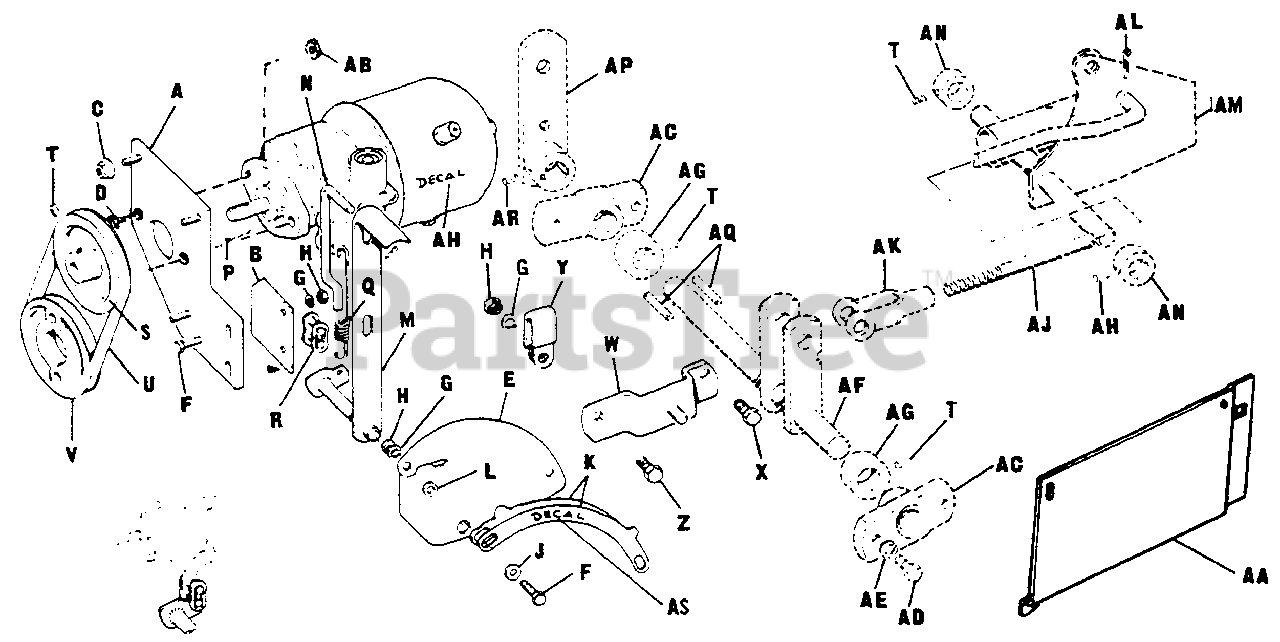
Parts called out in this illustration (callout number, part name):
A	Pump Support Assembly
B	Angle Bracket
C	Hex. Nut, Whiz Lock, 5/16"-18
D	Machine Screw, Flat Hd. 3/8-16 x 1-1/4" lg.
F	Hex. Cap Screw, 1/4"-20 x 3/4"
G	Lock Washer, 1/4"
H	Full Hex. Nut, 1/4"-20
J	Plain Washer, 1/4"
K	Stop Plate
M	Lever Assembly
N	Latch Rod
P	Cotter Pin, 3/32" x 5/8"
R	Connecting Link
S	Pump Pulley
T	Set Screw, 5/16"-18 x 5/16"
V	Drive Pulley
W	Pivot Bar Assembly
X	Hex. Cap Screw, 5/16"-18 x 1"
Y	Hose Clamp
Z	Hex Cap Screw, 1/4"-20 x 1"
AA	Panel, Side L. H.
AB	Nut, Whiz-Lock, Flange, 3/8-16
AC	Lift Lever Bearing
AD	Hex. Cap Screw, 3/8"-16 x 7/8"
AE	Lock Washer, 3/8"
AF	Lift Shaft Assembly
AG	Set Collar
AJ	Lift Rod (497 only)
AK	Adj. Yoke End (497 only)
AL	Cotter Pin, 1/8" x 1" (497 only)
AM	Tiller Lift Assy. (497 only)
AN	Set Collar (497 only)
AP	Front Lift Lever Assembly
AR	Set Screw, 5/16"-18 x 1/4" (497 only)
AS	Film (157232 on 569)
